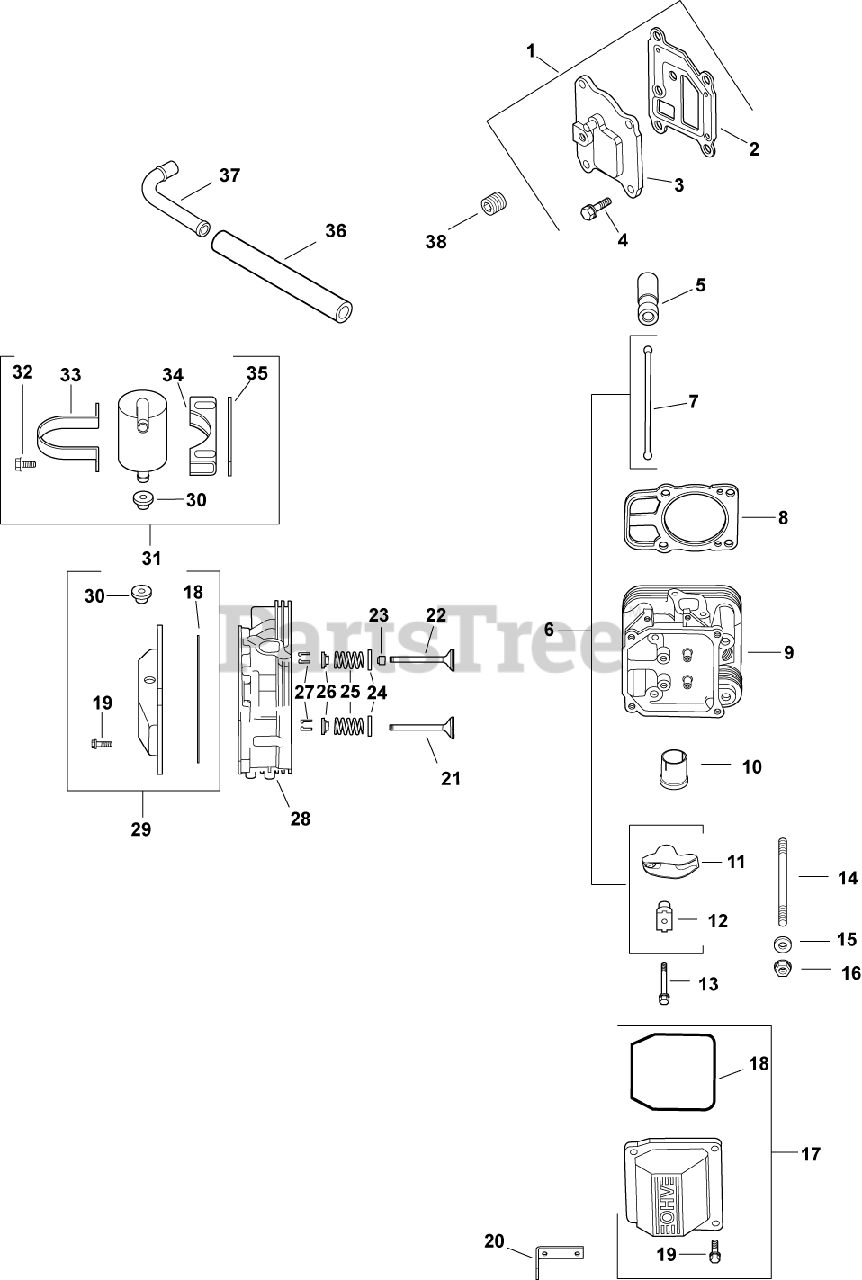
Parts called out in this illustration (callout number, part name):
1	KIT, BREATHER COVER W/GASKET
2	GASKET, BREATHER-USE 24 041 67-S
3	COVER, BREATHER -USE 24 096 125-S
4	SCREW,FLG THD FRM M6X1.0X20-(#25086396S)
5	LIFTER, HYDRAULIC VALVE-USE 25 351 10-S
6	KIT, VALVE TRAIN
7	ROD, PUSH
8	CYL HEAD GASKET KIT-USE 24 841 04-S
9	HEAD, ASSEM CYLINDER #2 -USE 24 318 116-
10	LINER, EXHAUST PORT-USE 24 605 07-S
11	ARM, ROCKER
12	PIVOT, ROCKER ARM
13	SCREW, FLG M6X1.0X34
14	STUD, M8X1.25
15	WASHER, FLAT 8.6 MM
16	NUT, FLG M8X1.25
17	KIT, VALVE COVER-PLAIN
18	O-RING (YELLOW) -USE 24 153 30-S
19	SCREW, FLG M6X1.0X30
20	STRAP, LIFTING-USE 25 445 03-S
21	VALVE, EXHAUST (STD) - USE 32 016 01-S
22	VALVE, INTAKE (STD)
23	SEAL, VALVE STEM - (#2503214S)
24	RETAINER, SPRING
25	SPRING, VALVE
26	RETAINER, VALVE SPRING - USE 25 173 28-S
27	KIT, RETAINER
28	HEAD, ASSEM CYLINDER #1 -USE 24 318 108-
29	KIT, VALVE COVER
30	GROMMET, RUBBER
31	KIT, BREATHR SEPARATR-(#24755241S)
32	SCREW,FLG THD FRM M5X0.8X16-(#25086398S)
33	STRAP, BREATHER - USE 24 755 241-S
34	BRACKET, BREATHER SEPARATOR
35	SPACER
36	HOSE, BREATHER (WAWB)-USE 24 326 63-S
38	PLUG, CTSK PIPE 1/8"
2401602-S	VALVE, EXHAUST (.25)
2401702-S	VALVE, INTAKE (.25)
